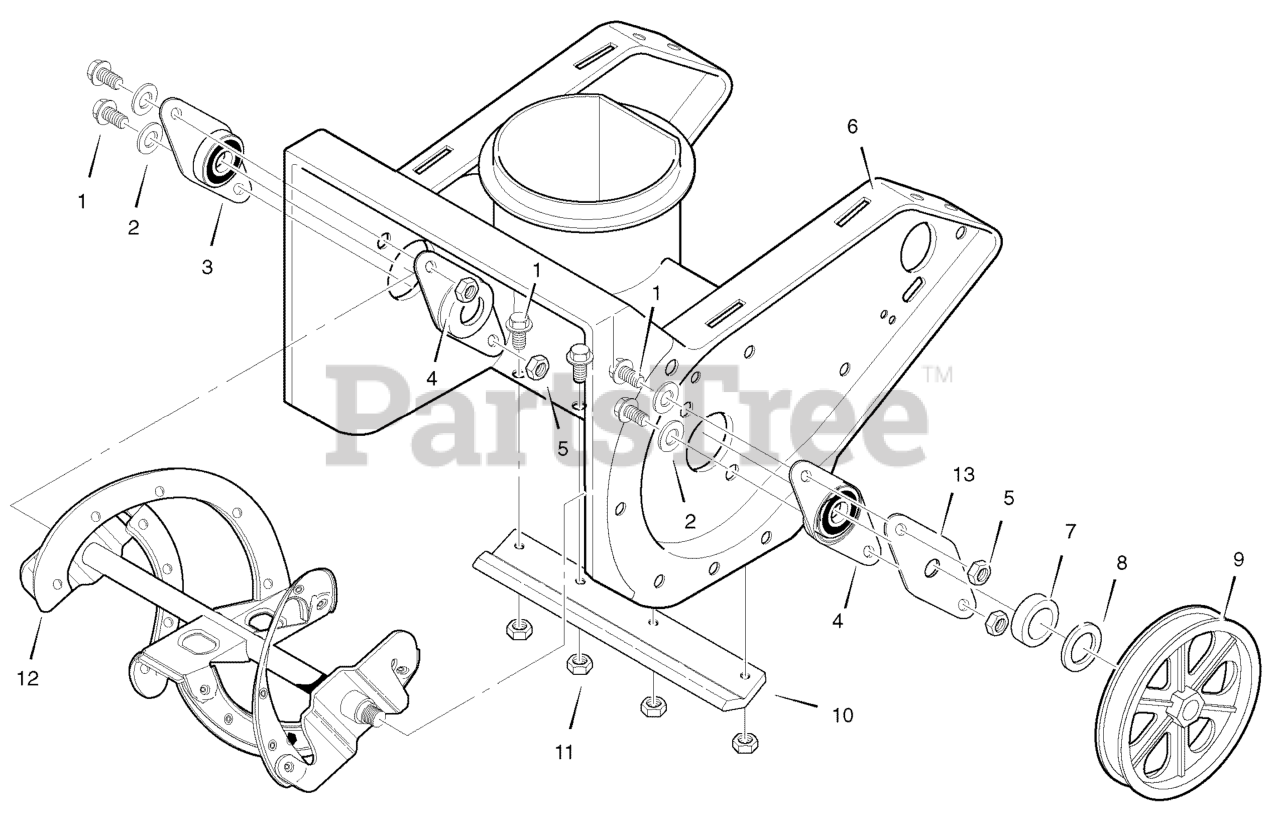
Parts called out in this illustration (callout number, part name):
1	SCREW .25-20X.63
2	WASHER, FLAT .281x.63x.065
3	PLATE, BEARING RETAINER
4	PLATE & BEARING ASSY
5	NUT, LOCK .25-20
6	AUGER HOUSING 21"
7	SPACER, SLEEVE
8	WASHER, FLAT .640x1.25x.06
9	PULLEY, POLY V
10	SCRAPER BLADE
11	NUT, LOCK .25-20
12	AUGER ASSY
13	RETAINER BEARING
